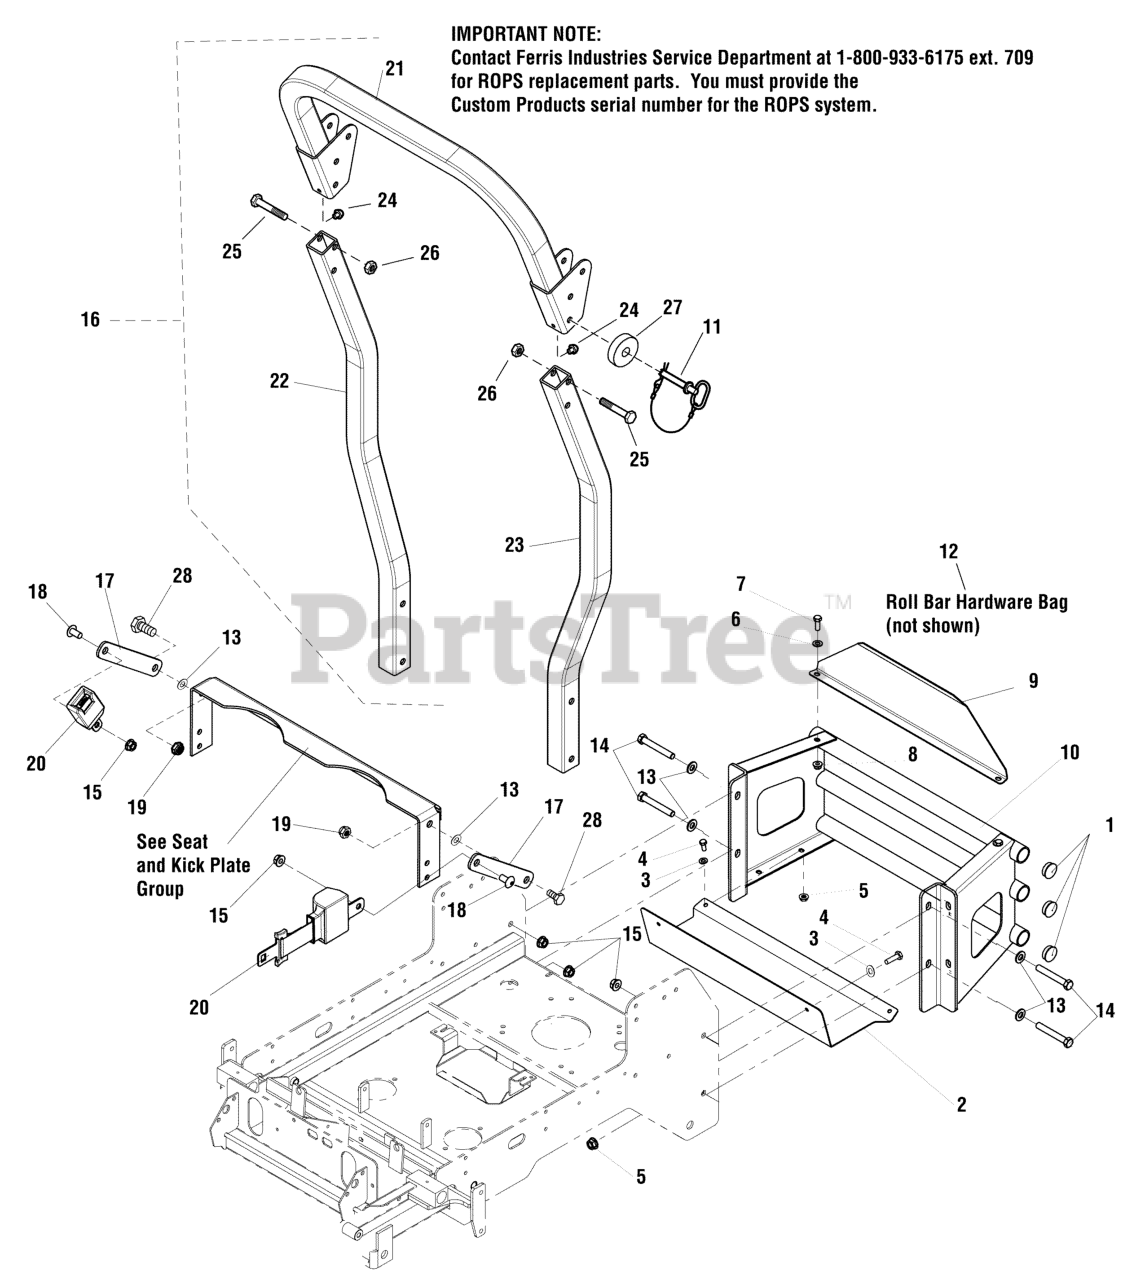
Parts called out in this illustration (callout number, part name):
1	PLUG, PANEL, 1.25 - BLACK
2	PLATE, HEAT SHIELD - RED
3	WASHER, 5/16" SAE
4	BOLT, 5/16-18 X 3/4 GD5
5	NUT, 5/16-18 HEX NYLOCK FLANGE
6	WASHER, 3/8 SAE
7	BOLT, 3/8-16 X 1" GD5 CZ
8	NUT, 3/8-16 HEX NYLOCK FLANGE
9	PLATE, CARB PROTECTOR - RED
10	WELD, BUMPER, IS2000Z - RED
11	PIN, HINGE W/ LANYARD
12	HARDWARE BAG, IS1500Z/1S2000Z
13	WASHER, 1/2 SAE
14	BOLT, 1/2-13 X 3-1/4, HEX HD, GD5, CZ (SV)
15	NUT, Hex Flange, Nylock, 1/2-13
16	ROPS (Call 1-800-933-6175 ext. 2193 if replacing a ROPS)
17	PLATE, SEAT BELT ANCHOR - BLK
18	SCREW, 1/2-13 X 1.00, SHCS
19	NUT, 1/2-13 HEX NYLON LOCK
20	SEAT BELT, RETRACTING - ASSM
21	ROLL BAR TOP LOOP
22	ROLL BAR POST, RH
23	ROLL BAR POST, LH
24	BUMPER, ROPS
25	* BOLT
26	* NUT
27	WASHER, EPDM FOAM, 1/2" ID
28	BOLT, 1/2-13 X 1-1/4 GD5 CZ
